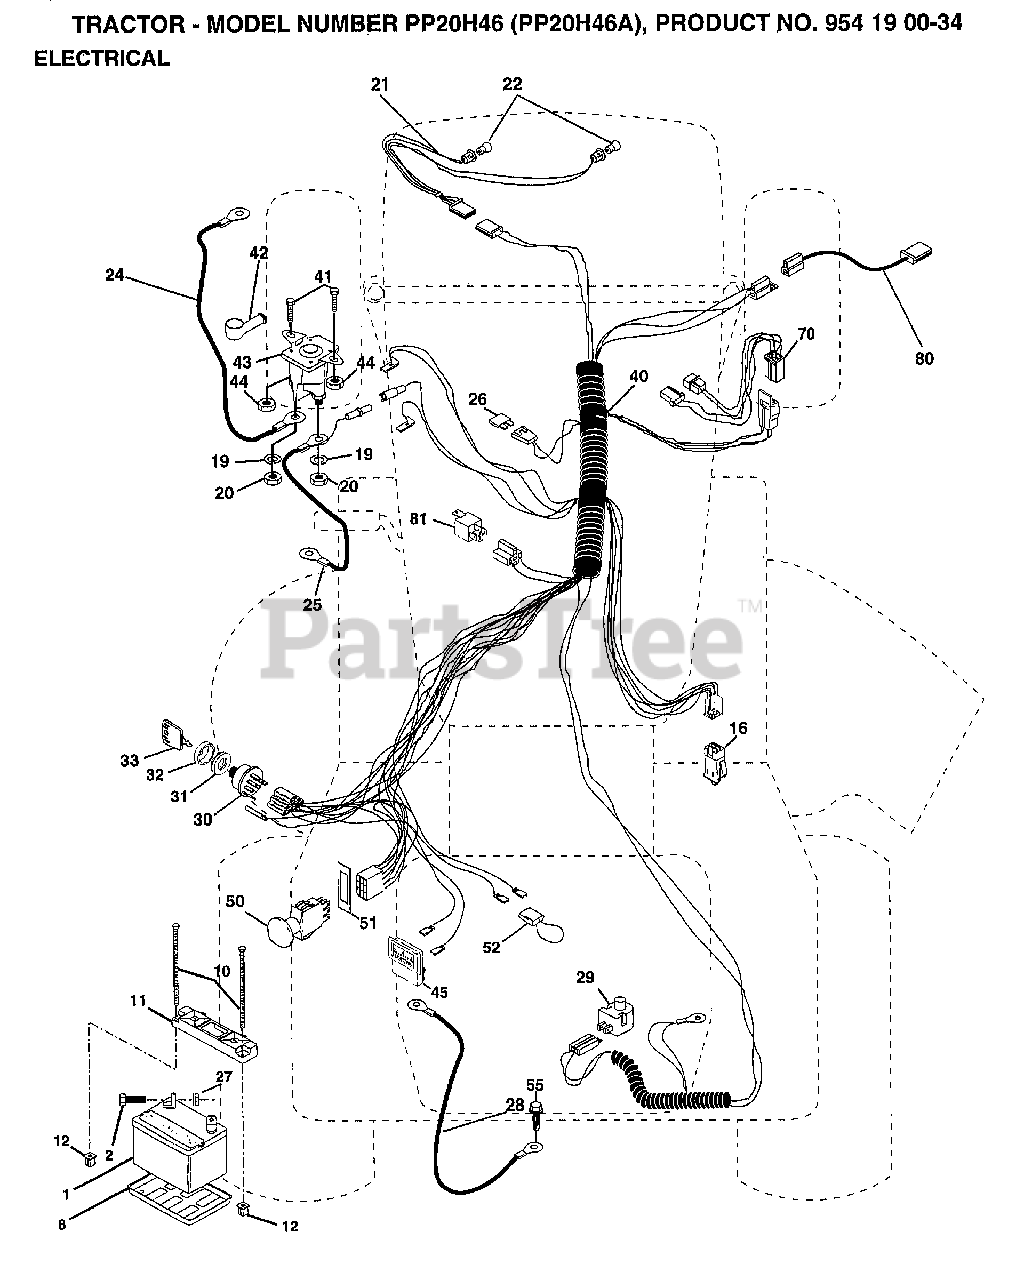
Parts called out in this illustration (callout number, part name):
2	BOLT LT
8	"TRAY T, BATTERY"
11	HOLDDOWN BATTERY
16	SWITCH INTERLOCK
20	NUT
21	HARNESS.ASM.LIGHT W/4152J
22	HEADLAMP BULB
24	"CABLE T, BATTERY"
25	CABLE.6GA.22W/16W
26	FUSE.15 AMP
27	NUT
28	CABLE.GRND.6GA.21
29	SWITCH.PLUNGER
30	SWITCH IGN 4POS
31	NUT IGNITION
32	COVER KEY SWITCH
33	KEY
40	HARNESS.IGNITION
41	BOLT HXHD FIN
44	NUT HXKEP 1/4X20
45	AMMETER
50	PTO SWITCH.BLK
51	RING RETAIN PTO
52	PROTECTION LOOP
55	SCREW LT
70	HARNESS.ENGINE
80	HARNESS.CLUT.EVX.
81	RELAY ASSY T
